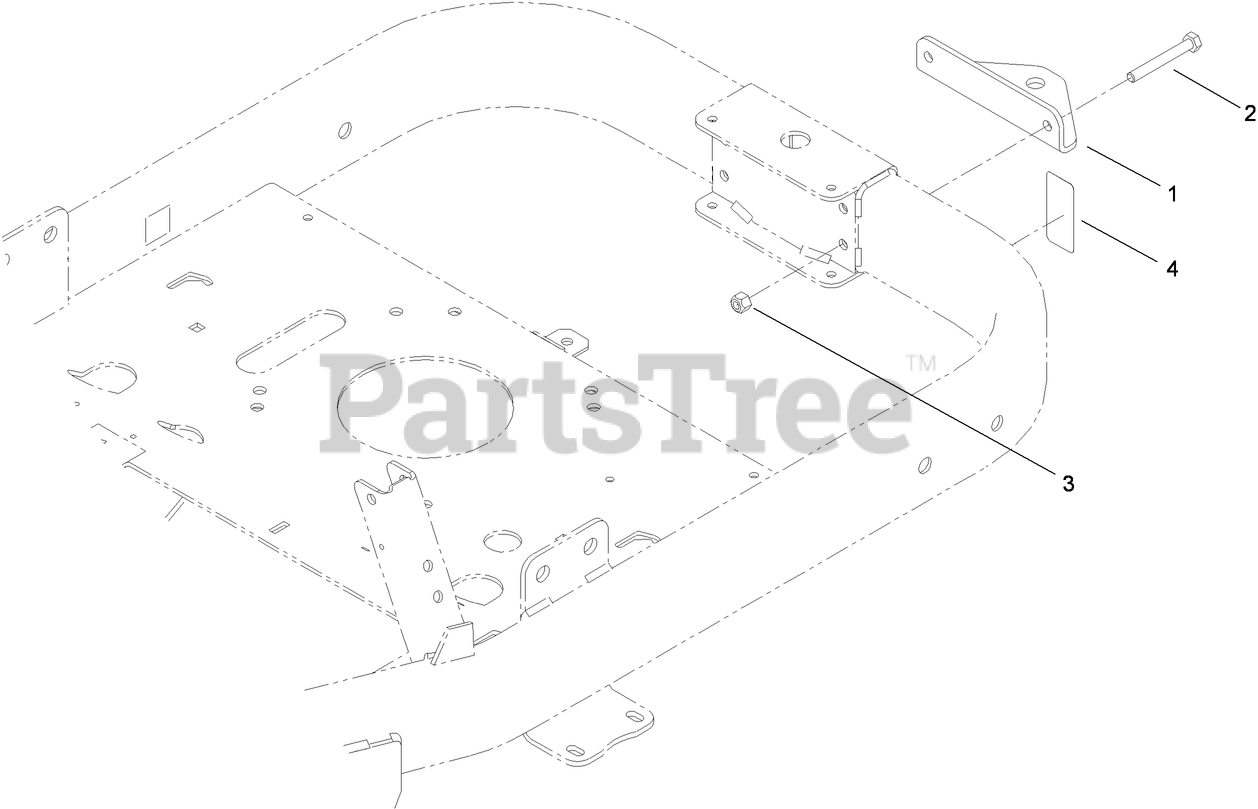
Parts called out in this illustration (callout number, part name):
1	BRACKET-HITCH
2	SCREW-HH
3	NUT-LOCK, NI
